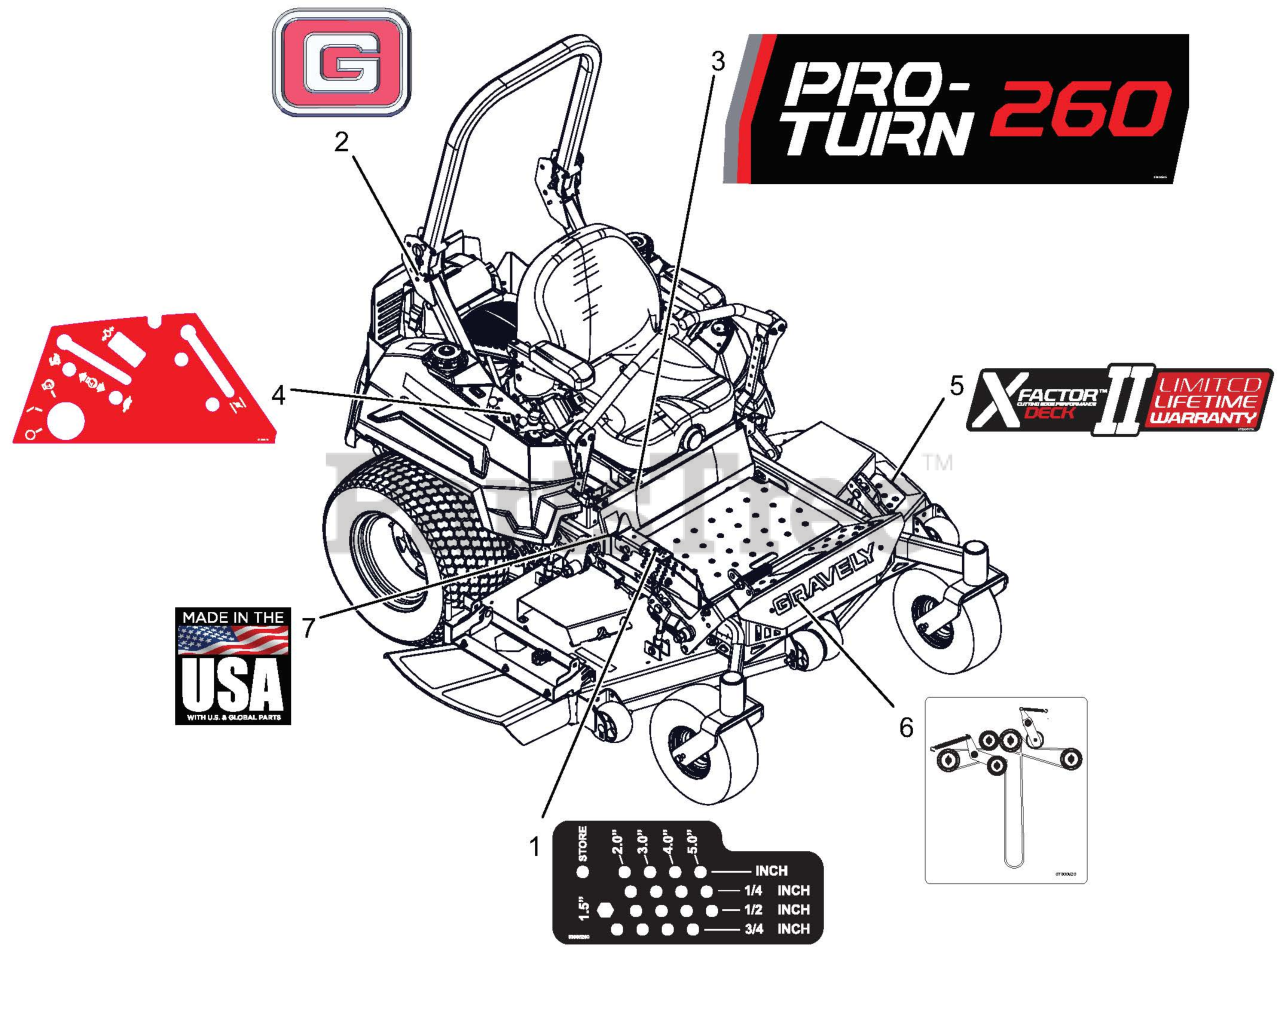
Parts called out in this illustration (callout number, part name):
1	DECAL, HEIGHT OF CUT
2	DECAL, GRAVELY BRAND
3	DECAL, PRO-TURN 260
4	DECAL, NON-EFI CONTROL PANEL
5	DECAL, X-FACTOR DECK
6	DCL,BELT ROUTE-RH BK-SIDE IDLR
7	DECAL, MADE IN USA
